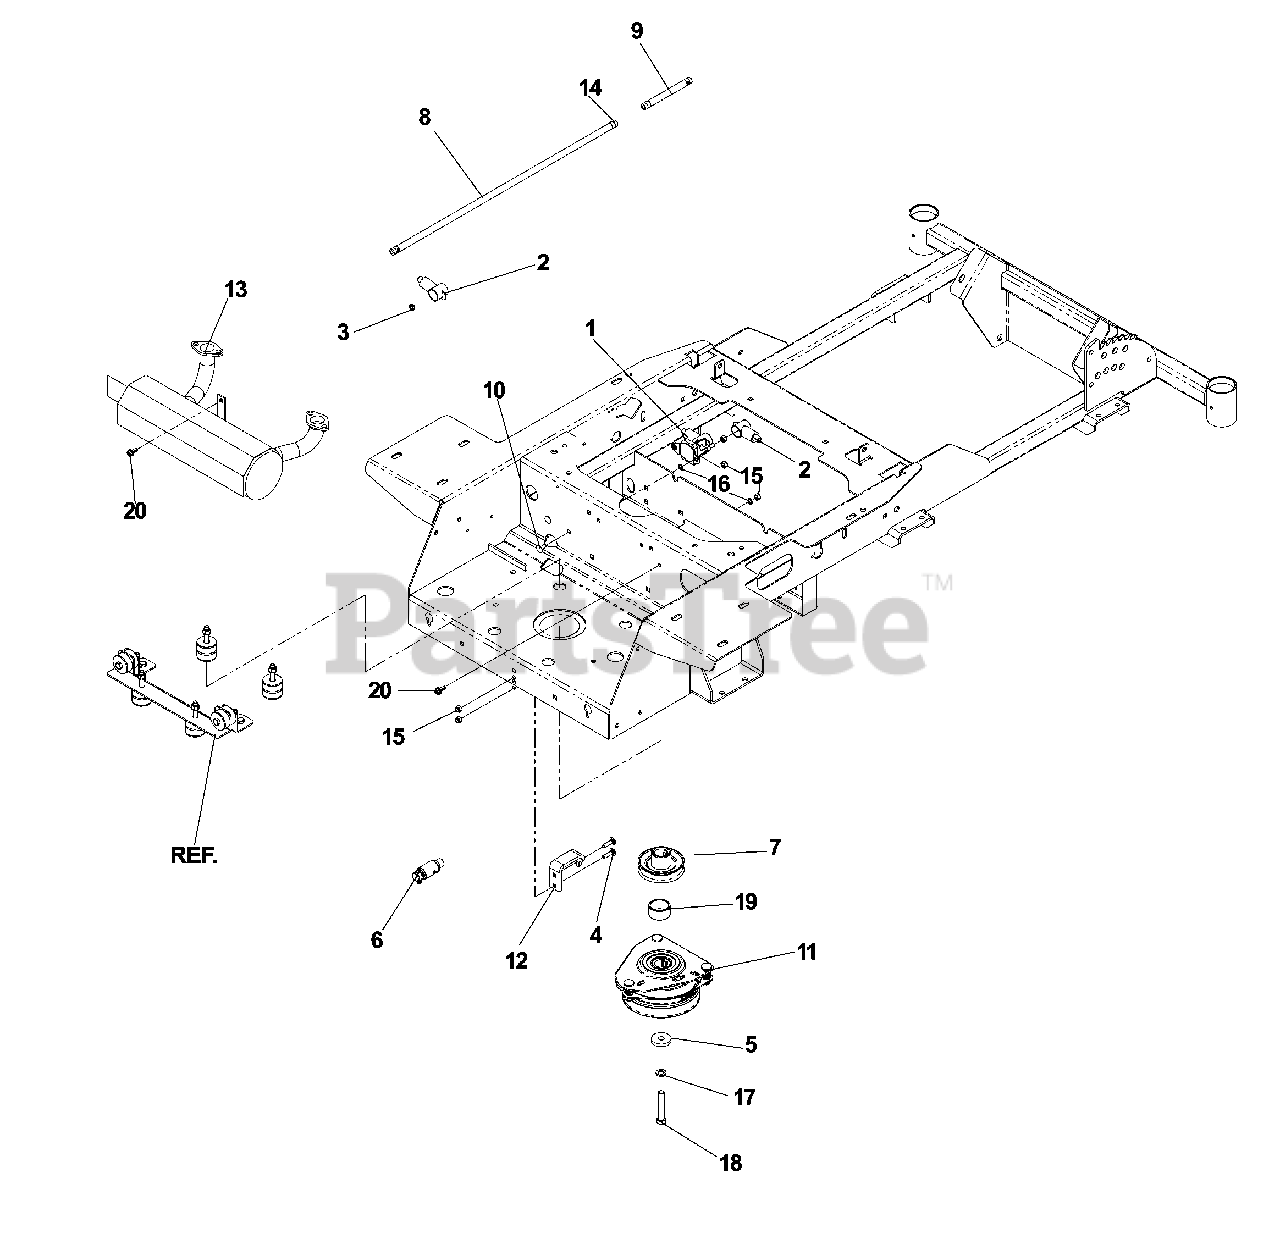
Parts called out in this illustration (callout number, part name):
1	SOLENOID
2	INSULATOR
3	JAM NUT 1/4C
4	RHSNB, 1/4-20 X 1, GR5
5	CLUTCH, WASHER
6	OIL DRAIN FITTING
7	PULLEY, ENGINE
8	FUEL LINE 24"
9	FUEL LINE 5"
10	RHSSNB, 1/4-20X5/8
11	CLUTCH, OGURA - 90 FT/LB
12	TIE DOWN, CLUTCH
13	MUFFLER
14	HOSE CLAMP
15	NUT 1/4-20 NYLOC
16	WASHER 1/4 INT TOOTH
17	WASHER 7/16 LOCK
18	HEX SCREW 7/16-20 X 3
19	SPACER, ENGINE - PULLEY
20	SCREW- 1/4-20 X 5/8
